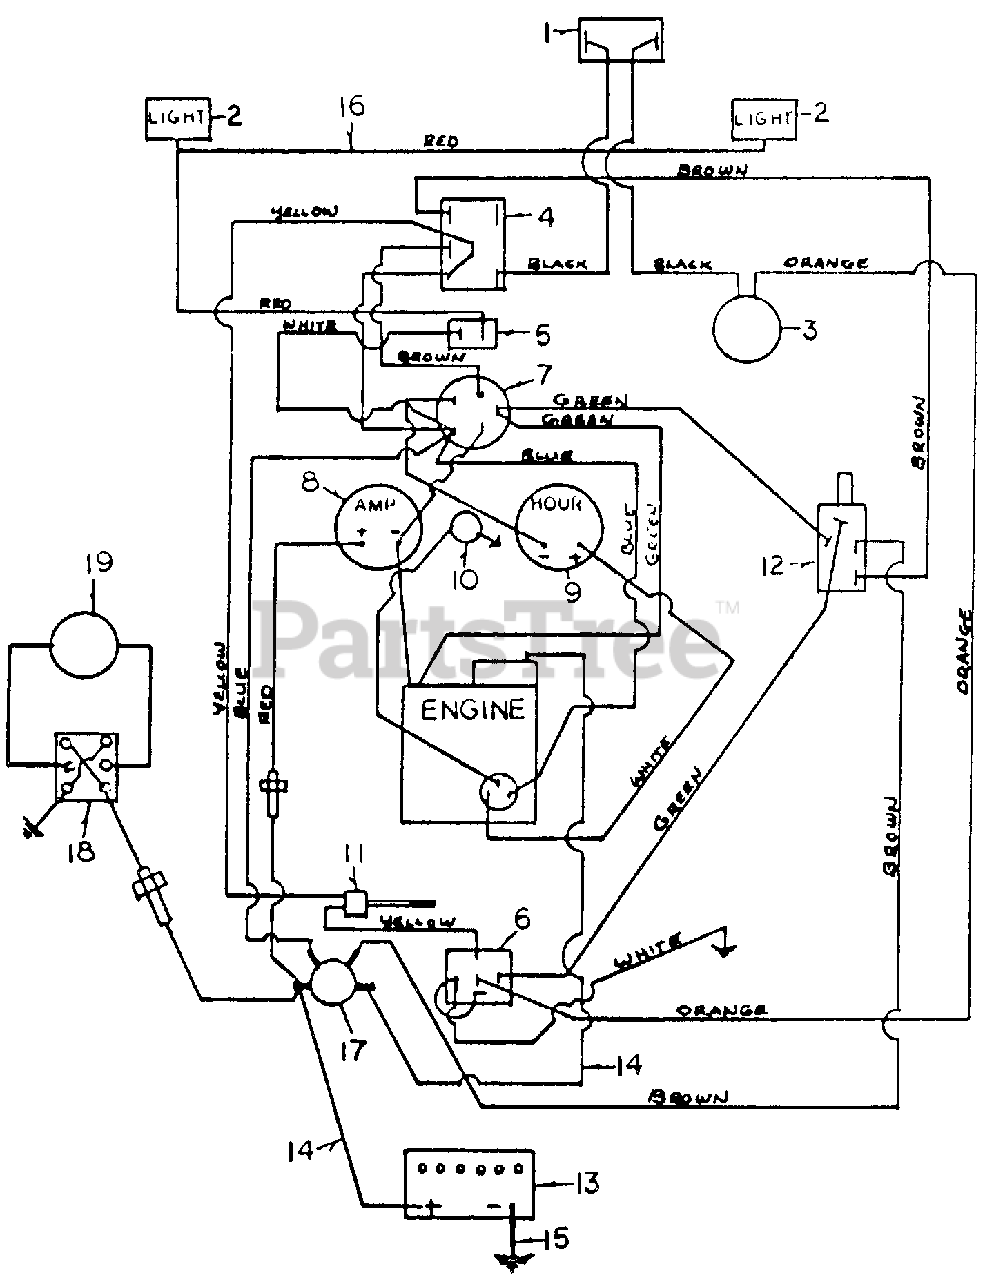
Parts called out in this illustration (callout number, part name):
1	10 Amp Clrcuit Breaker
2	Headlight Assembly
3	Electric Clutch Assembly
4	PTO Clutch Switch
5	Light Switch
6	Relay
7	Ignition Switch
13	Battery
16	Light to Switch Wire
18	3 Position Deck Lift Switch
19	Electric Lift Actuator
